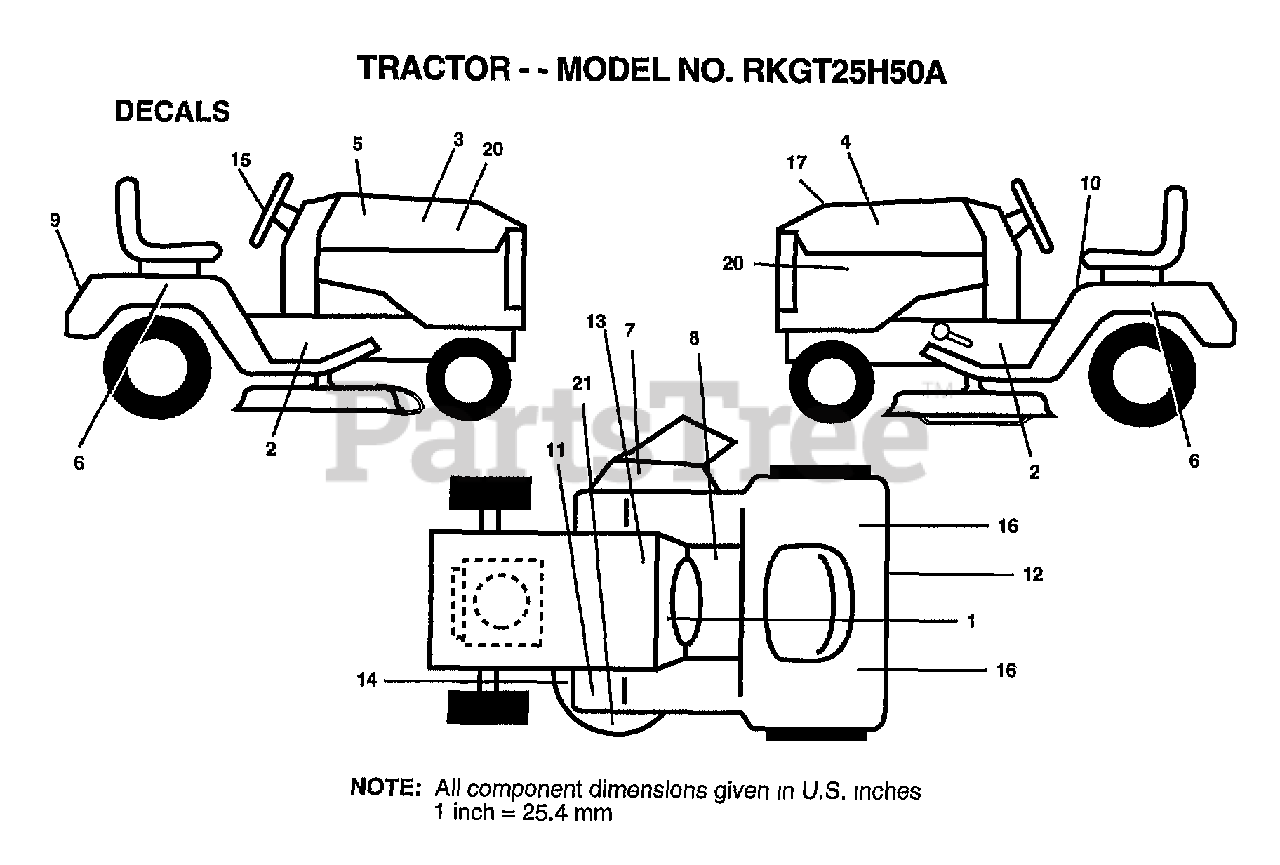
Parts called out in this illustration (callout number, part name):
1	DECAL OPER INSTR.
2	DECAL, CHASSIS
3	DECAL.HOOD.RH
4	DECAL.HOOD.LH
6	DECAL.FENDER.SIDE
7	"DECAL, WARNING"
8	DECAL BRAK PARK
9	DECAL.FNDER.LOGO
10	DECAL.CAUT.ENG/FR
11	DECAL T
12	DECAL D-BAR CNTRL
13	DECAL.BATRY.3-3908
15	DECAL.STRNG.WHL
16	REFLECTOR-TAIL YT
17	DECAL.RPLT.RKGPGRO
20	DECAL.DASH
